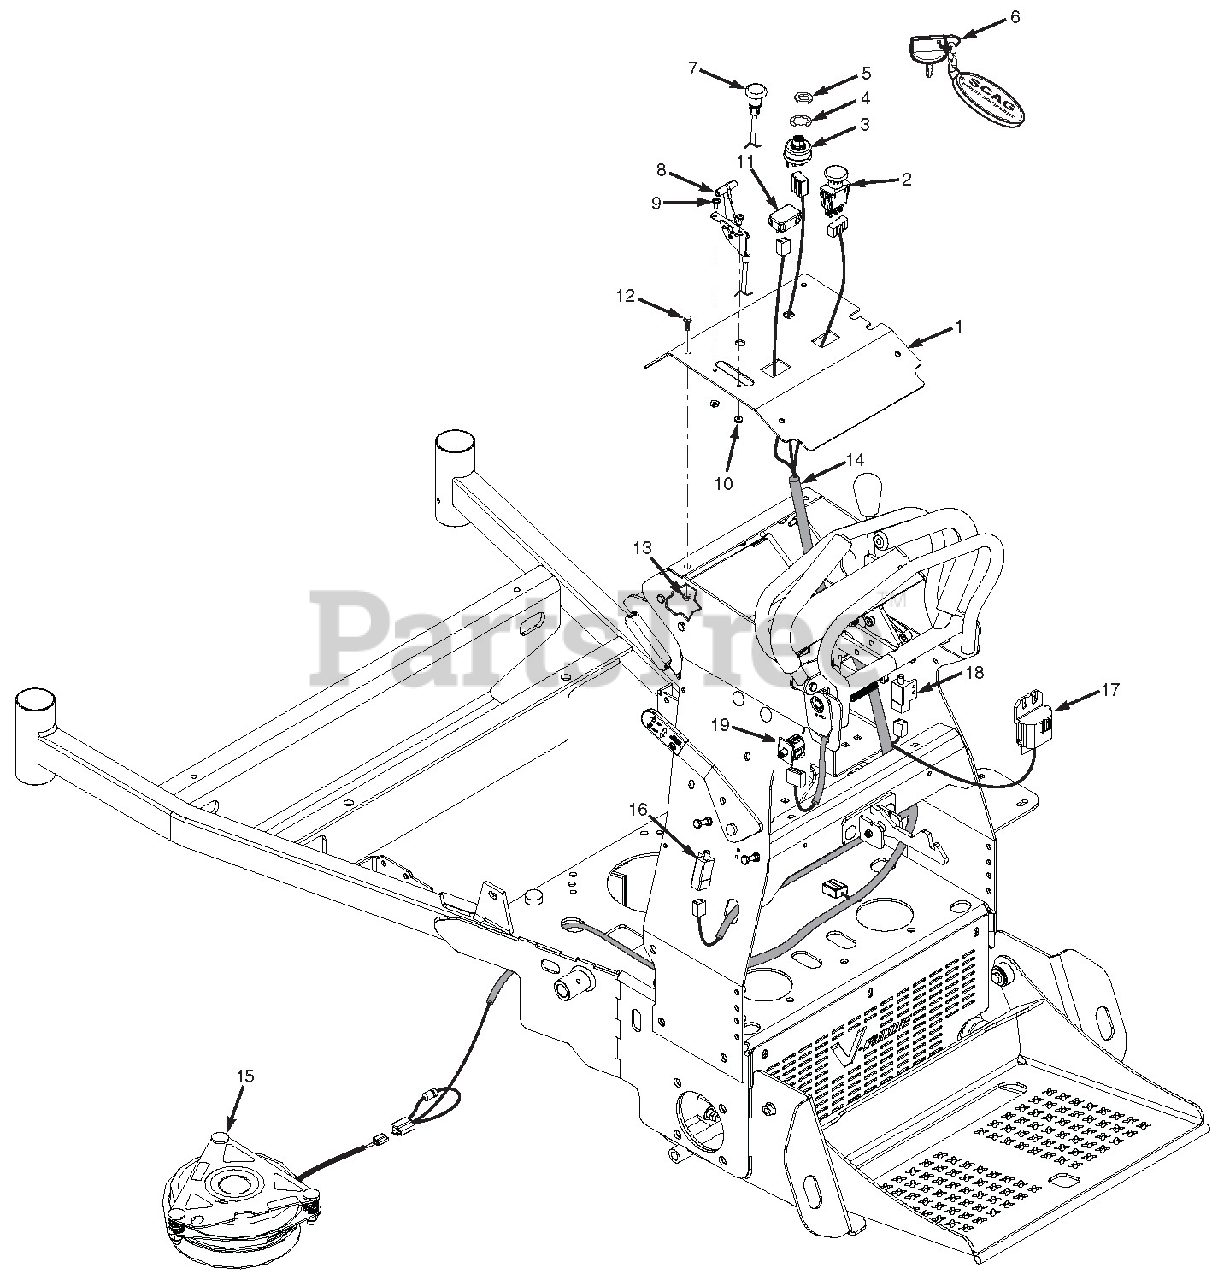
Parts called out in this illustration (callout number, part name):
1	Instrument Panel w/Decal
2	Switch, PTO - 10 Amp
3	Key Switch
4	Lockwasher, 5/8" Internal Tooth
5	Nut, 5/8-32 Special
6	Key Chain w/ Keys
6	Key w/Shroud
7	Choke Control, SVR
8	Throttle Control, SVR
9	Bolt, Carriage #10-24 x 1/2"
10	Locknut, #10-24
11	Hourmeter
12	Bolt, Hex Head 1/4-20 x .63
13	Nut, Serrated Flange 1/4-20
14	Wire Harness, SVR Recoil Start
15	Clutch w/Tag (36A, 48V, 52V)
16	Switch, Interlock
17	Module, Safe Start
18	Switch, Interlock
19	Switch, Double Pole - Plunger
